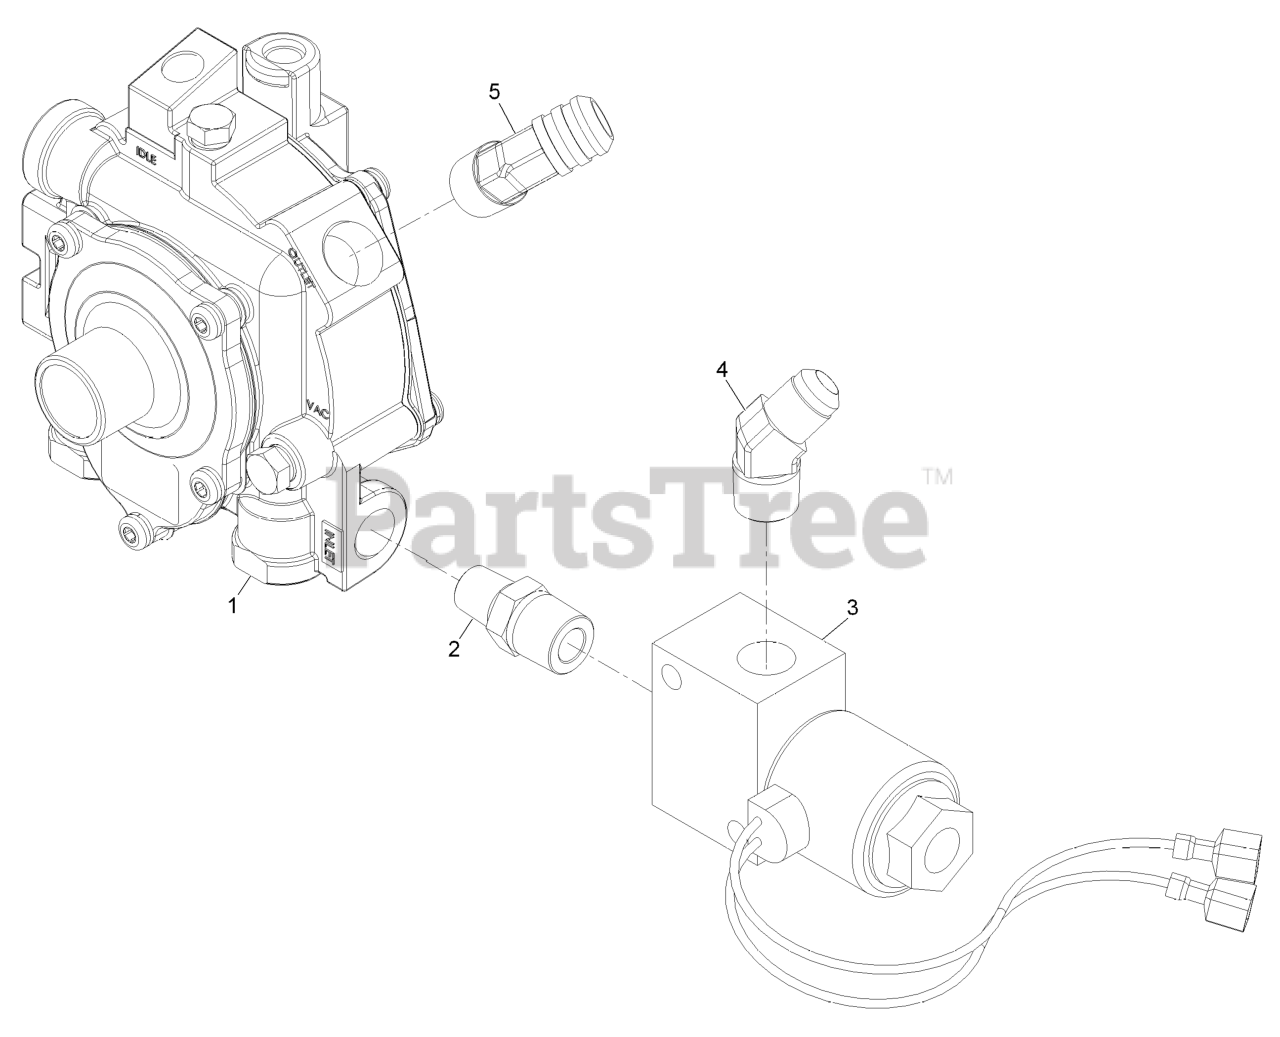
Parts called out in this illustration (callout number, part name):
1	REGULATOR-LPG
2	COUPLING-PIPE, MALE
3	LPG SOLENOID VALVE ASM
